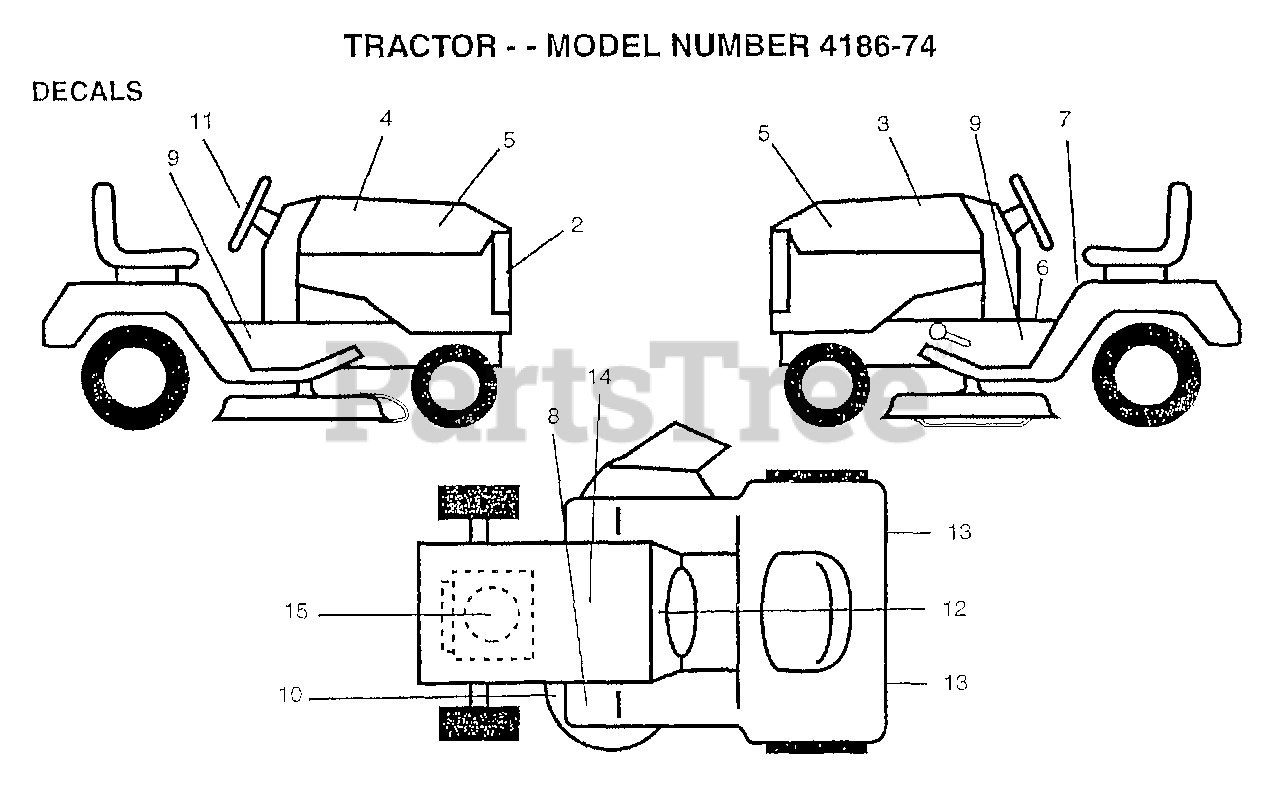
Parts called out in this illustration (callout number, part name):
2	GRILL DECAL
3	HOOD DECAL LH
5	NAMEPLATE LOGO
6	DECAL BRAK PARK
7	"DECAL DANGER,FEND"
9	DECAL CHASSIS
10	"DECAL.V.BELT.44"""
12	"DECAL-OPER,GEAR D"
13	REFLECTOR-TAIL YT
14	DECAL.BATRY.3-3908
15	DECAL, HP ENGINE
